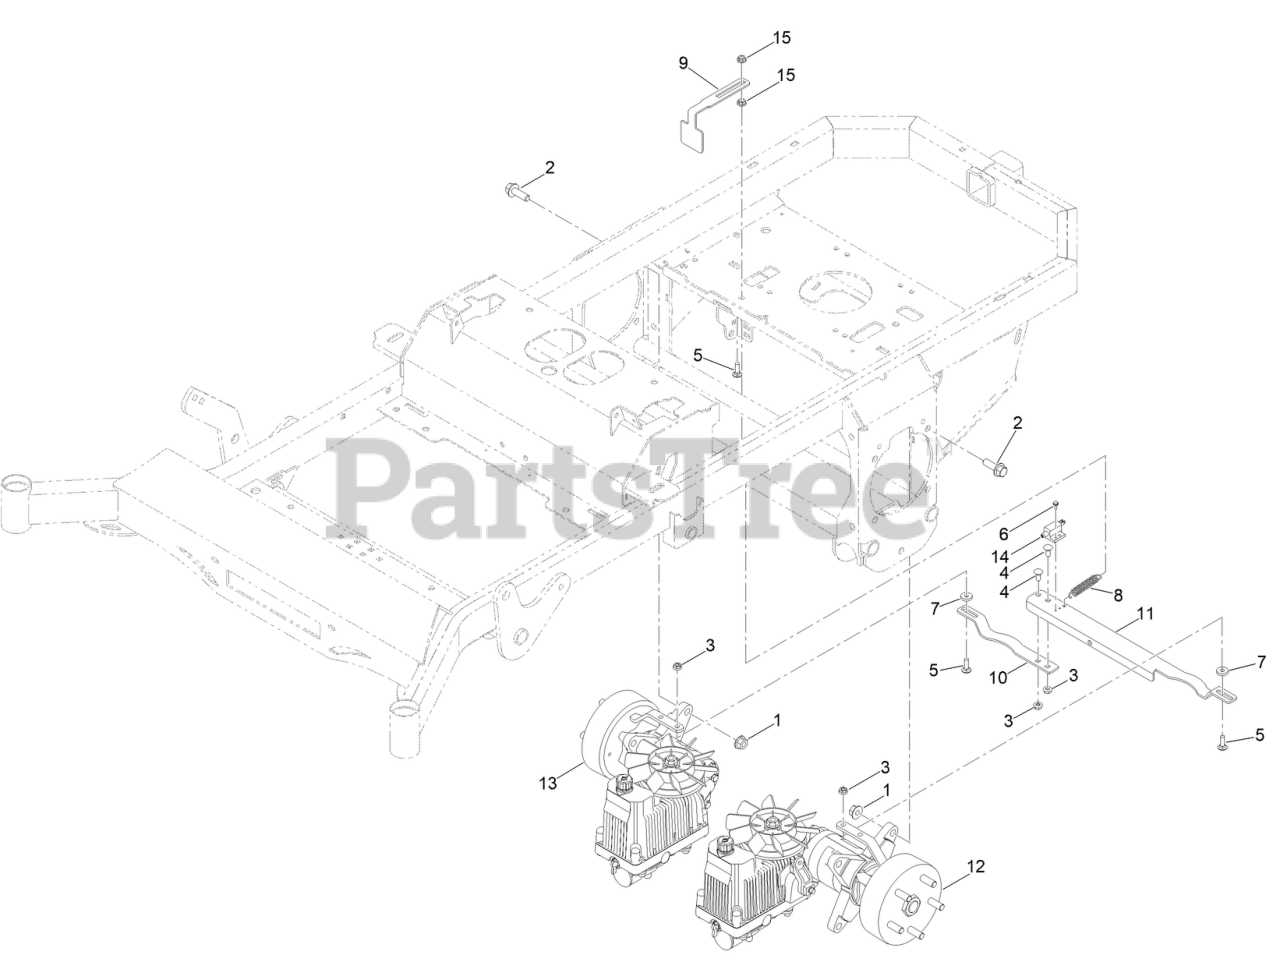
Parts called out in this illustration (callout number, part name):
1	NUT-HHF
2	SCREW-HHF
3	5/16-18 NYLON INSERT FLANGE L/NUT ZC
4	BOLT-CARR
5	BOLT-CARR
6	8-32 X 1/2 IND. HWH SLOT TYPE F TCS ZINC
7	.312 ID X .875OD X .1875 THK F/W NYL
8	MWR BRAKE PEDAL RELEASE SPRING
9	STAND TRANS BRAKE INTERLOCK BRKT PAINT
10	MWR PARK BRAKE BRKT RT PAINT
11	MWR PARK BRAKE BRKT LT PAINT
12	HTJ12 PARKER LT SIDE HYDROSTATIC TRANSM
13	HTJ12 PARKER RT SIDE HYDROSTATIC TRANSM
14	NO PLUNGER LIMIT SWITCH
